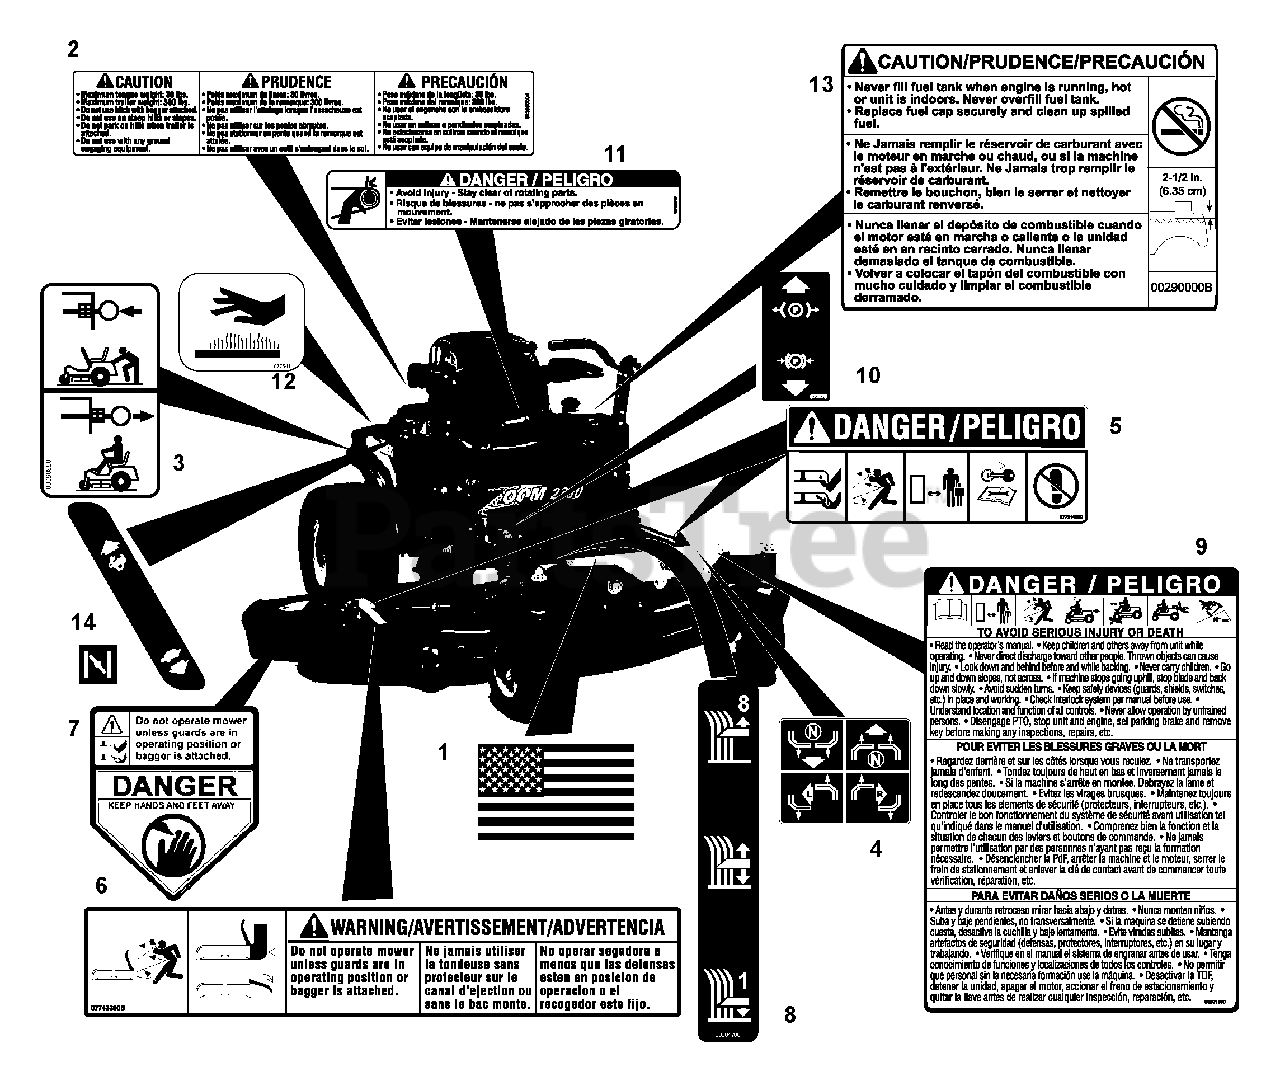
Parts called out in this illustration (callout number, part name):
1	DECAL, AMERICAN FLAG
2	DECAL, TRAILER HITCH
3	DECAL, TRANSMISSION DISCONNECT
4	DECAL, INSTRUCTIONAL-STEERING
5	DECAL, MOWER PAN DANGER
6	DECAL, WARNING
7	DECAL, CPSC DANGER
8	DECAL,CUT HEIGHT
9	DECAL, DANGER BILINGUAL
10	DECAL, PARKING BRAKE LEVER
11	DECAL- DANGER
12	DECAL, HOT SURFACE
13	DECAL,FUEL WARNING
14	DECAL, SPEED CONTROL
